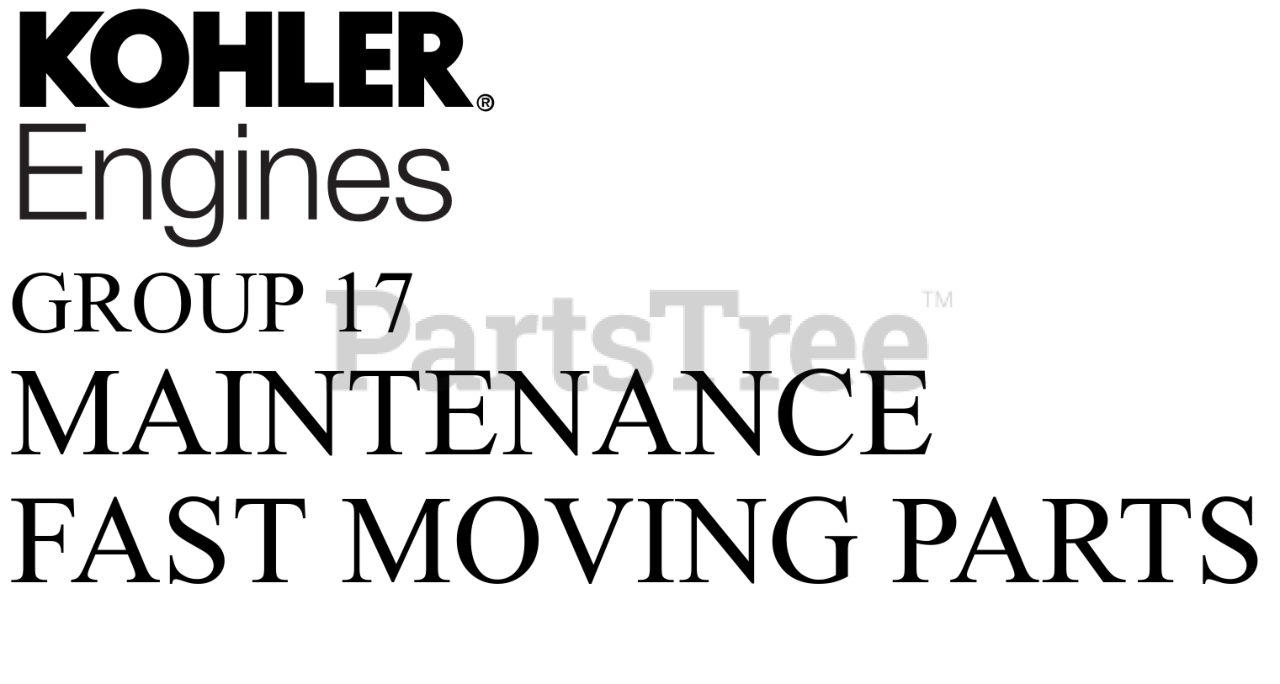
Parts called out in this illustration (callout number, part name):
NI	FILTER, BREATHER
NI	FILTER, FUEL
NI	ELEMENT, AIR FILTER - PRIMARY
NI	ELEMENT, AIR FILTER - SAFETY
NI	KIT, HDAC MAINTENANCE
NI	OIL FILTER
NI	SPARK PLUG
